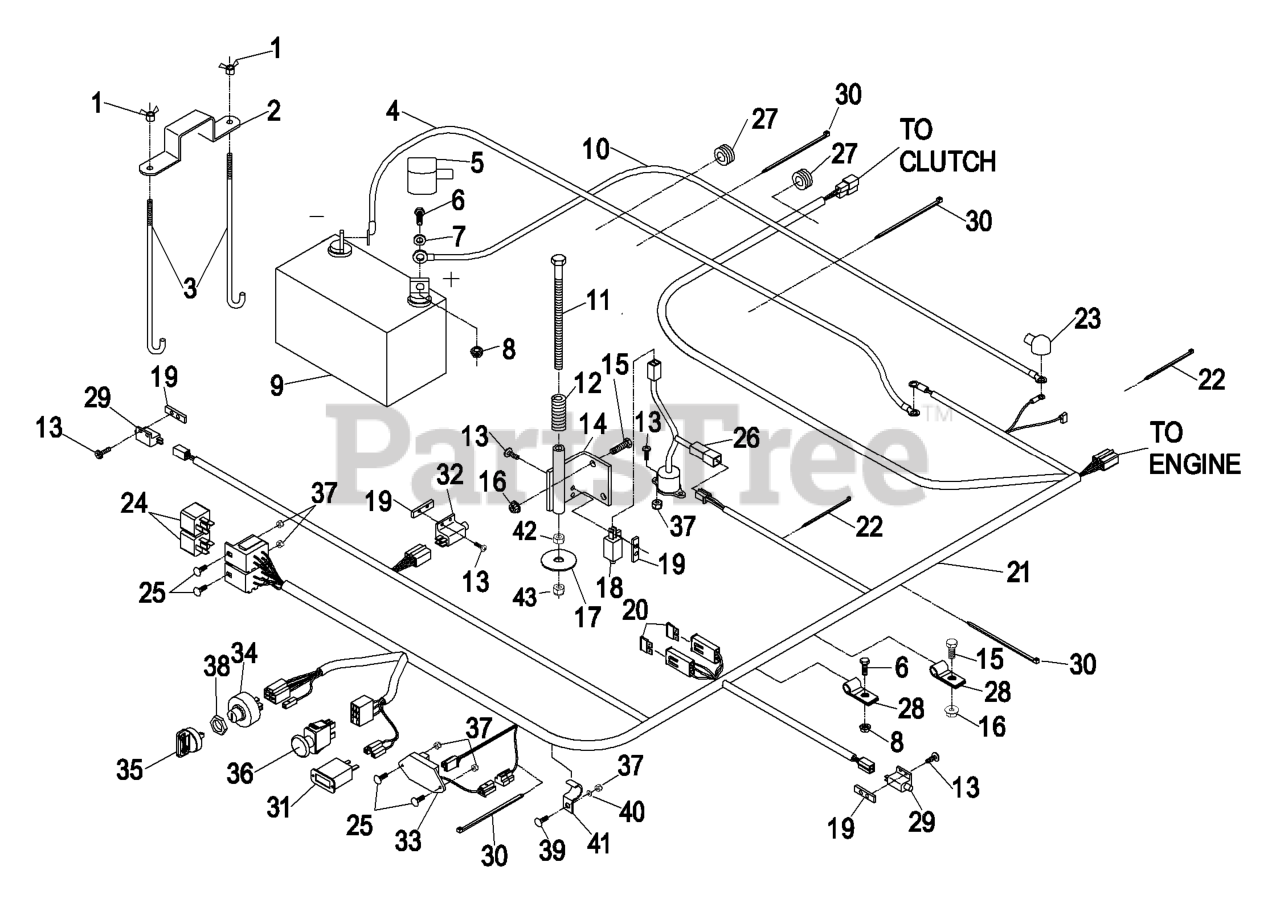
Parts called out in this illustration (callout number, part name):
1	WINGNUT
2	STRAP-HOLDDOWN
3	BOLT-HOLDDOWN
4	CABLE-GROUND, NEGATIVE
6	SCREW-HH
7	WASHER-FLAT
11	SCREW-HH
12	SPRING-SWITCH, SEAT
13	SCREW-PPH
14	BRACKET-SWITCH, SEAT
15	SCREW-HH
18	SWITCH-CLOSED, NORMALLY
19	PLATE-TAPPED
20	FUSE-BLADE TYPE, 20 AMP
21	HARNESS-WIRE
22	TIE-CABLE
23	INSULATOR-SOLENOID
25	BOLT-CARR
27	GROMMET
28	CLIP-LOOM
29	SWITCH-OPEN, NORMALLY
30	TIE-PLASTIC
31	METER-HOUR
33	MODULE-DELAY, SEAT
35	KEY-IGNITION
37	NUT-LOCK, NI
38	NUT-SWITCH, IGNITION
39	BOLT-CARR
40	WASHER-FLAT
41	CLIP-HALF, LOOM
42	NUT-HEX
43	NUT-LOCK, NI
